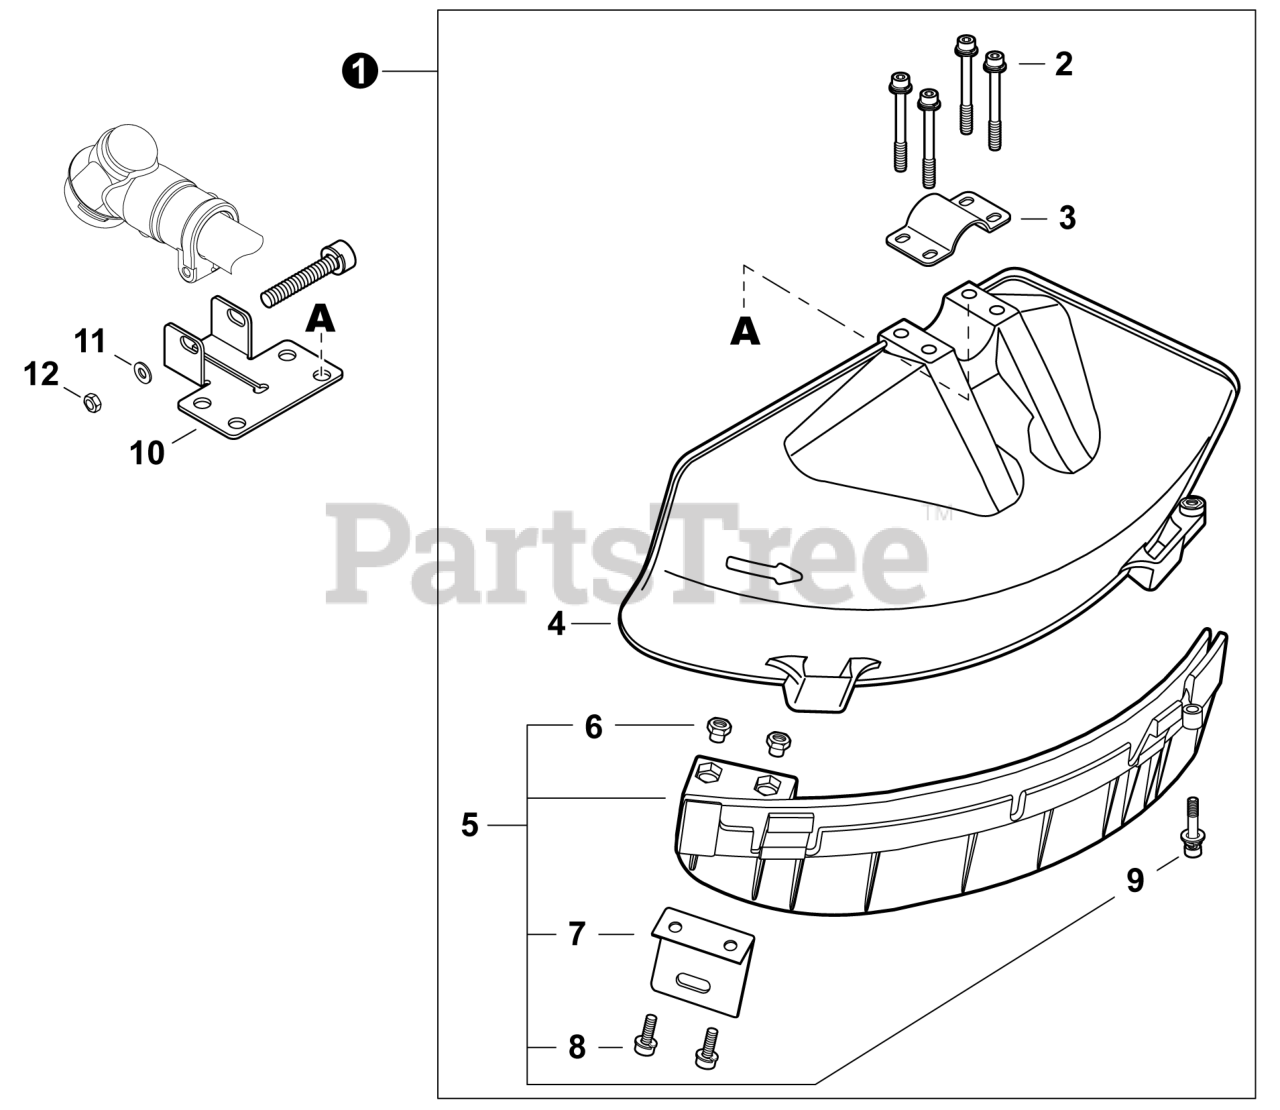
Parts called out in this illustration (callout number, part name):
1	DEBRIS SHIELD KIT
2	BOLT M5×45
3	CLAMP, UPPER
4	SHIELD, DEBRIS - BLADE
5	DEBRIS SHIELD EXTENSION ASSY
8	BOLT 5×16
9	BOLT M5×22
10	CLAMP, LOWER
11	WASHER 6.5×13×1
12	NUT, HEX M6
